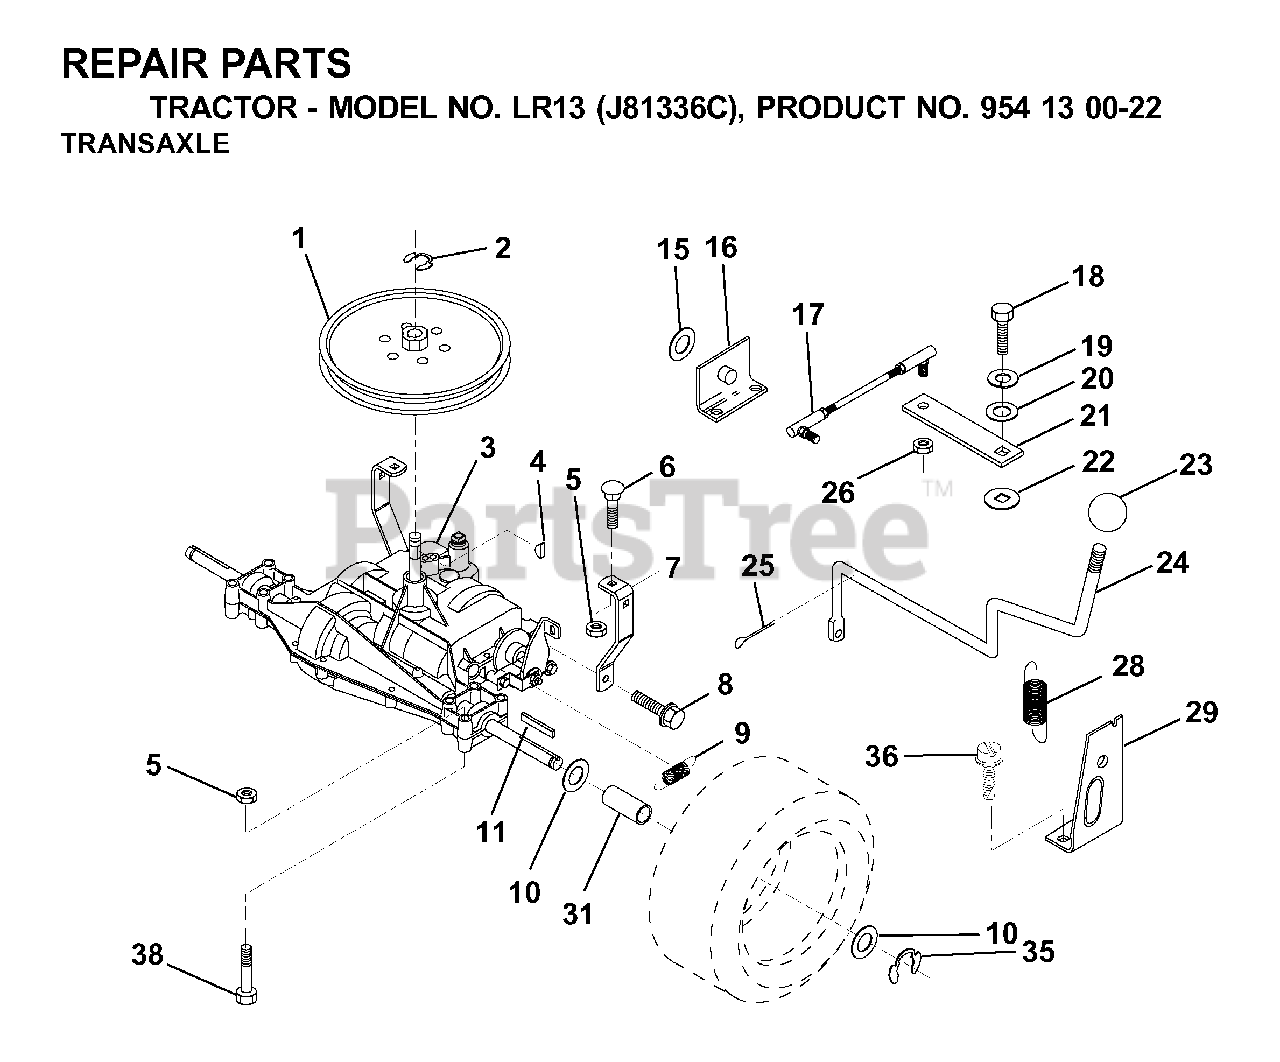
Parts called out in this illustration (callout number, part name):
2	RETAINING RING LT
5	LOCKNUT
6	BOLT
7	STRAP,TORQUE
8	SCREW 5/16"
9	SPRING,BRAKE RETURN
11	SQUARE KEY
15	WASHER
16	SUPT, HDLE SHT LH
18	BOLT 1/4-28X3/4
19	LOCKWASHER
20	WASHER LT
22	WASH-SHFT PLT LT
23	KNOB.DUCKHEAD.1/2
24	ROD, SHIFT
25	PIN COTTER
26	LOCKNUT
28	SPRING.EXTENSION
29	SUPPORT HANDLE SHAFT RH
31	SPACER AXLE
35	E-RING LT
36	SCREW
